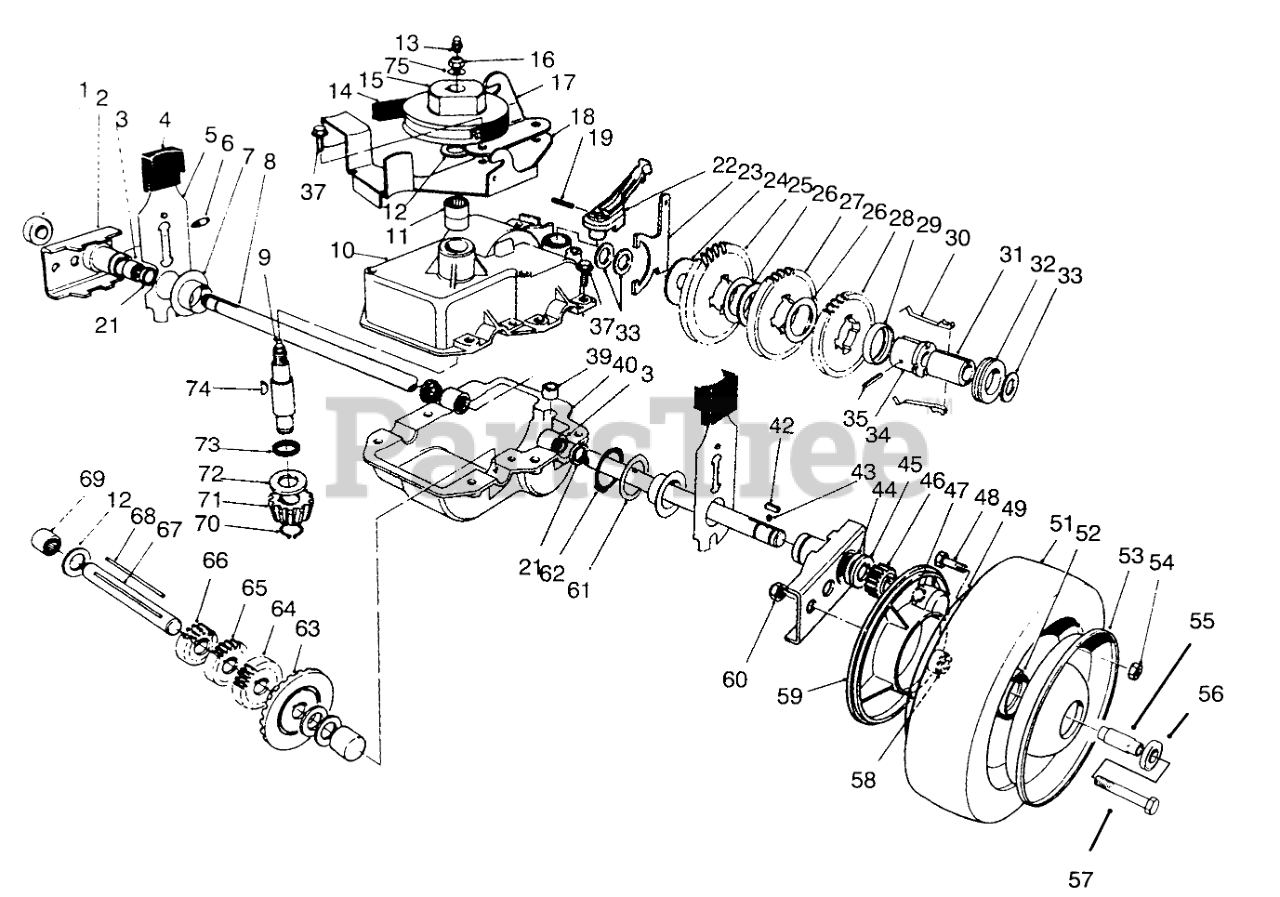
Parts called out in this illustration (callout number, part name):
1	BEARING-WHEEL
2	Pivot Arm Assembly (Incl Ref. #1,3,6,21)
3	BEARING-ROLLER
4	KNOB-ARM
5	REAR SPRING ARM ASM
7	CAP-END
8	SHAFT-OUTPUT
9	Shaft-Input (Incl Ref. #13)
10	Upper Case Assembly (Incl Ref. #11,73)
11	BEARING-NEEDLE
12	WASHER-THRUST
13	FITTING-GREASE, ZERK
14	V-BELT
15	PULLEY
16	NUT-HEX
17	Bracket-Traction Engage
18	Belt Guide Bracket
19	PIN-COIL
21	SEAL-OIL
22	LEVER-SHIFT
23	YOKE-SHIFT
24	WASHER
26	WASHER
27	GEAR-42T
28	GEAR-38T
29	RETAINER-KEY
30	KEY-SHIFT
31	SLEEVE
32	COLLAR-SHIFT
33	WASHER-PLAIN
34	SLEEVE-GEAR
35	PIN-GROOVE
37	SCREW-HWHTF
39	BUSHING-YOKE
40	CASE-GEAR, LOWER
43	SPRING-COMPRESSION
44	WASHER-THRUST, OUTER
45	WASHER-THRUST, OUTER
46	GEAR-PINION
47	RING-RETAINING
48	SCREW-HH
49	Wheel-Half
52	HUB-BEARING
53	Wheel-Half
54	NUT-LOCK, NI
55	SPACER-BEARING
56	BEARING-WHEEL
57	SCREW-HH
58	SPACER-COVER, WHEEL
59	COVER-WHEEL
60	NUT-LOCK, CONE
61	WASHER
62	RING-RETAINING
63	GEAR-BEVEL
64	GEAR-18T
65	GEAR-14T
66	GEAR-12T
67	SHAFT-INTERMEDIATE
69	BEARING-NEEDLE, CLOSED
70	RING-RETAINING
71	PINION-BEVEL
72	WASHER-THRUST
74	KEY-WOODRUFF
75	WASHER-FLAT
